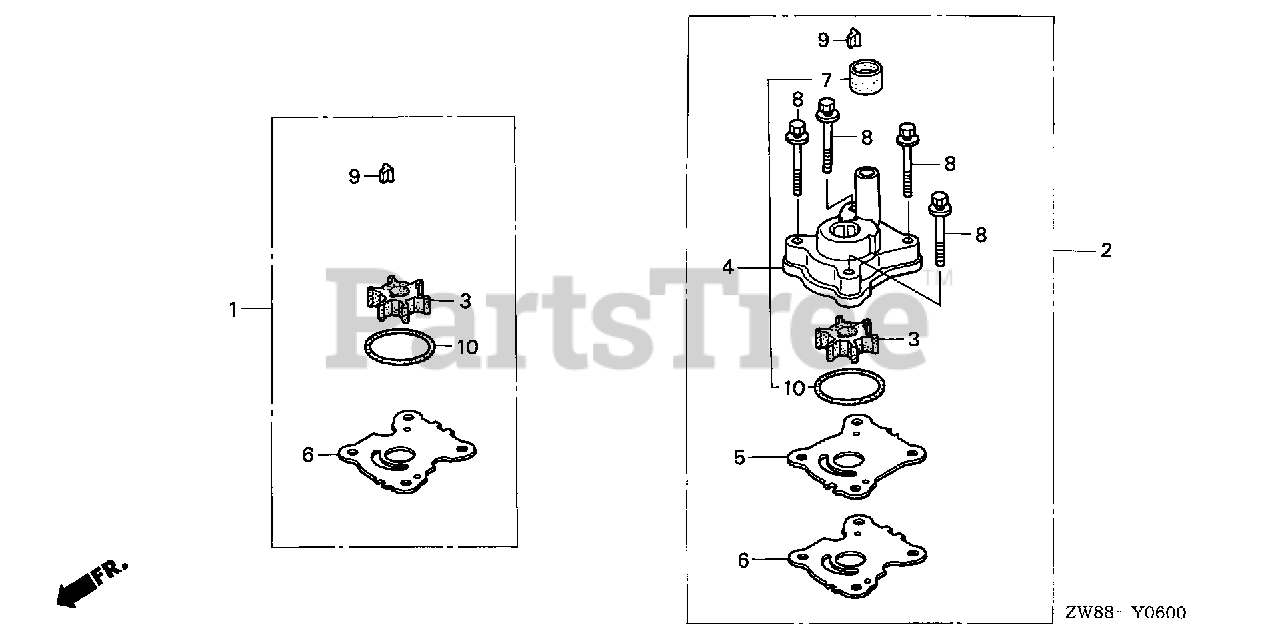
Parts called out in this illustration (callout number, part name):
1	PUMP KIT, IMPELLER
2	PUMP KIT, IMPELLER
3	IMPELLER, PUMP (S,L)
4	HOUSING ASSY., IMPELLER
5	COVER, IMPELLER
6	GASKET, IMPELLER
7	RING, WATER TUBE SEAL
8	BOLT-WASHER (6X50)
9	KEY, WOODRUFF
10	O-RING (42.2X2.4)
